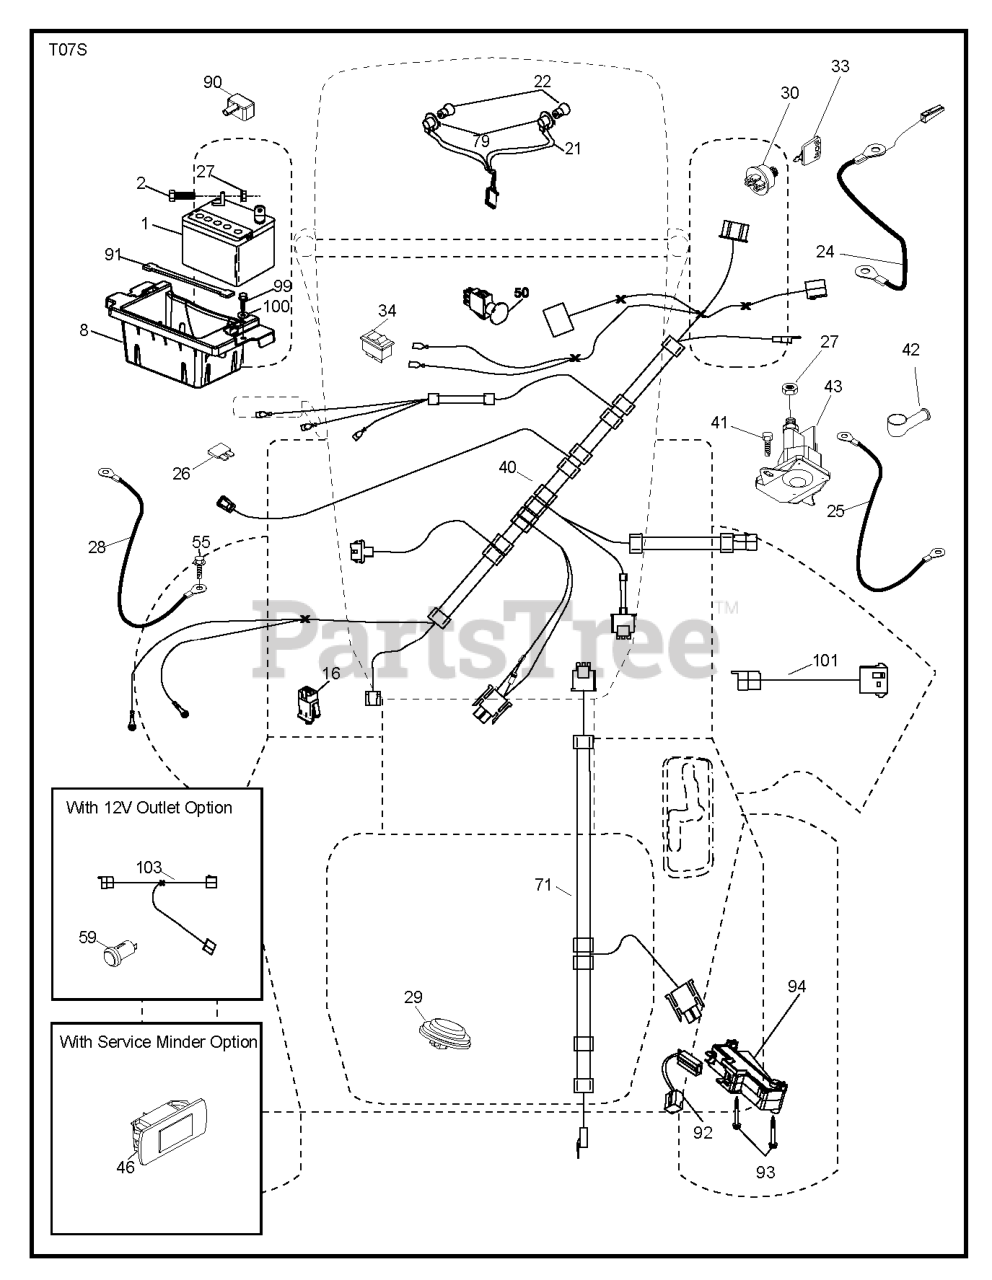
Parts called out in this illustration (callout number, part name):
1	Battery 12 Volt 25 Amp
2	BOLT.HEX.1/4.X.3/4.DICHROMATE
8	BOX.BATTERY.MOUNT.FRONT.LT
16	SWITCH INTERLOOK PUSH-IN
21	HARNESS ASSY LIGHT
24	CABLE.BATT.POS.WIRE.TG.DA SOL
25	CABLE.STARTER.6G.BL/RED.17.5
26	FUSE 20AMP
27	NUT
28	CABLE GROUND 6 GA 21" 90T BLK
29	SWITCH.SEAT.DELTA.OPC.
30	SWITCH.IGN.DELTA.W.LGH.ROS
33	KEY.CHAIN.BLISTER.PACK.GEN.INT
40	HARNESS.IGN.DASH.HUQ/P
41	SCREW
42	TERMINAL COVER
43	SOLENOID.W/BRASS.PLUNGER
46	RP.GUAGE.SRVCMNDR.HRMTR.
50	RP.PTO.SWITCH.8 TERMINAL.BLACK
55	SCREW 5/16"
59	OUTLET.12-VOLT
71	HARNESS-CHASSIS SUB
79	BULB HOLDER ASM.
90	COVER.TERMINAL.BATTERY
91	STRAP.BATTERY.MOUNT.FRONT(2 2)
92	HARNESS.PIGTAIL.CONSLE
93	SCREW.PLASTITE
94	MODULE.REVERSE.ROS
99	SCREW HEXWSHR 1/4-20X3/4
101	PIGTAIL.MATNLK.NEW.HAR
103	HARNESS PIGTAIL 12V OUTLET
